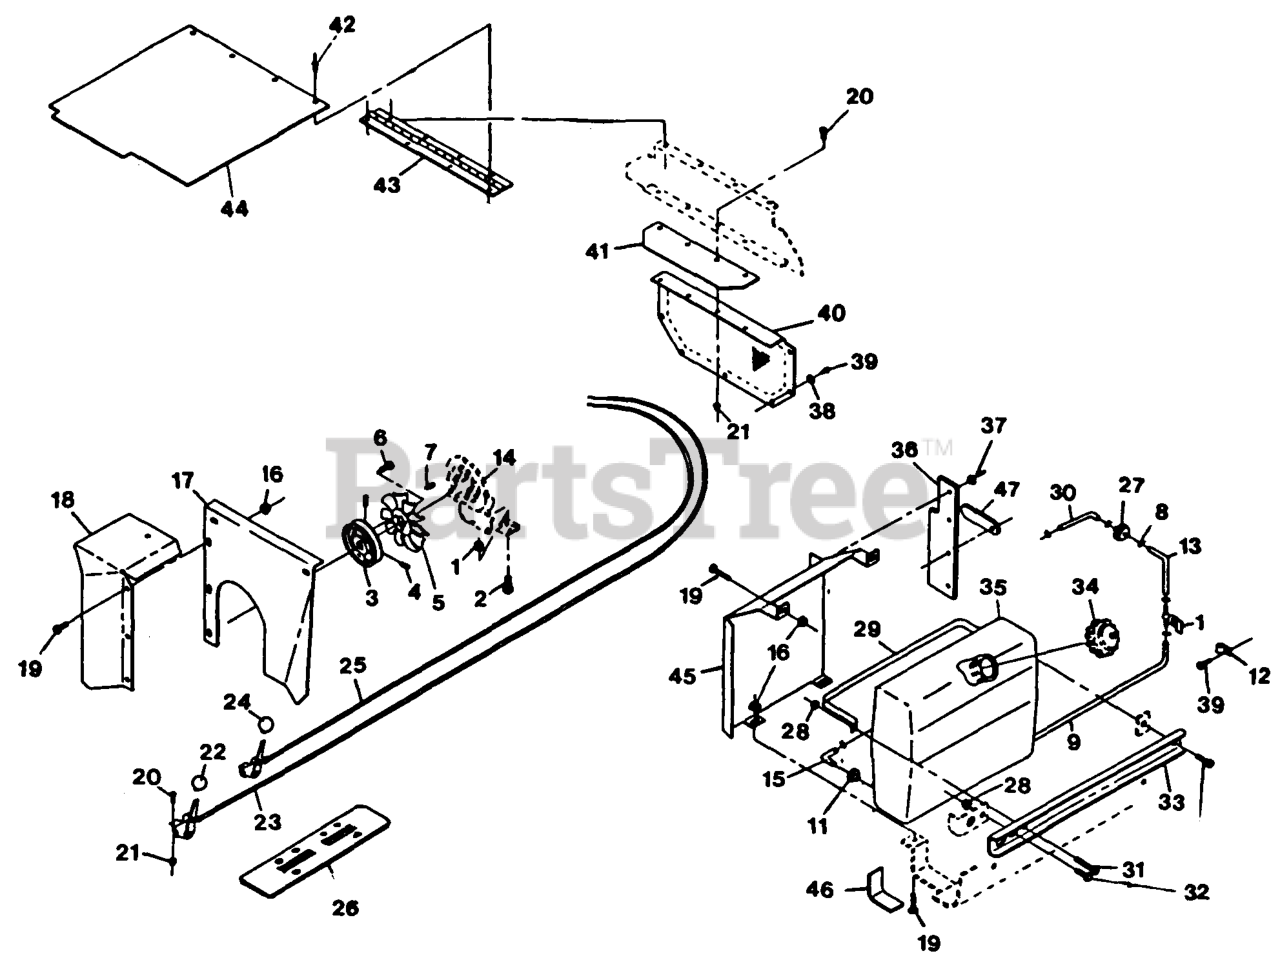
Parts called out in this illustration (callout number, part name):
4	SCREW-SET
9	FUEL LINE,19.0
10	VALVE-FUEL
12	CLIP-LOOM
14	Engine, Kohler Ch 20s
15	ELBOW-TANK, FUEL
17	SHIELD,HEAT FRONT
22	KNOB-BALL
23	CABLE,THROTTLE
24	KNOB-BALL, BLACK
25	CABLE,CHOKE
29	STRAP,FUEL TANK 3.8GAL
30	HOSE-FUEL
31	Bolt, Tap 1/4-20 X 2-1/2
34	CAP-FUEL
36	BAFFLE,ENGINE LH
37	RIVET-POP
42	Pop Rivet, Steel 3/16 X .250
43	HINGE,ENGINE COVER
45	SHIELD,HEAT FUEL TANK
46	PAD,FUEL TANK
47	CLIP-BAFFLE, REAR
